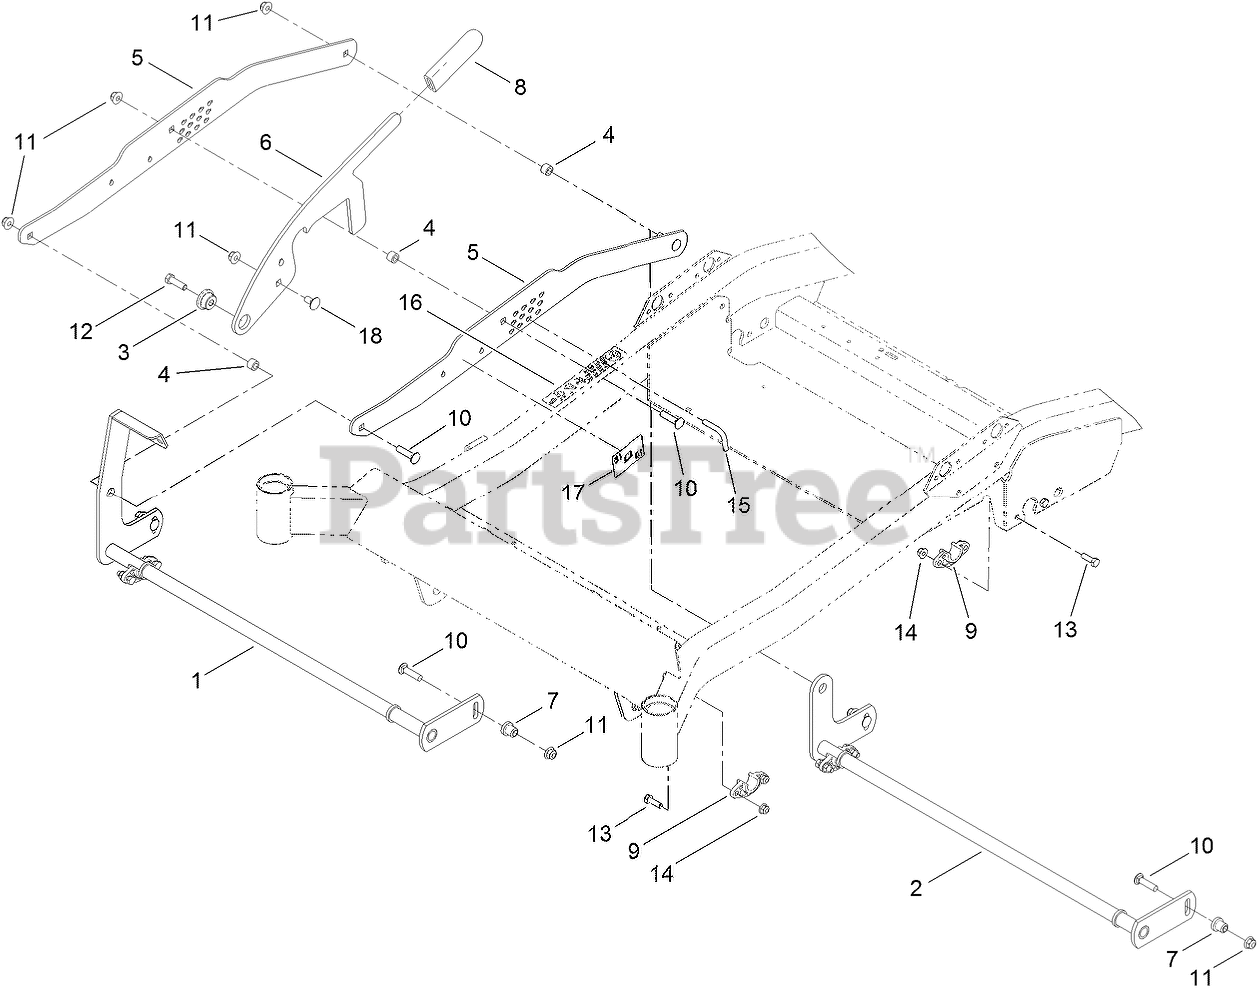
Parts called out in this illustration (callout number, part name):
1	PIVOT-FRONT
2	PIVOT-REAR
3	BUSHING-MOUNT, HOC
4	SPACER
5	PLATE-LIFT, FOOT
6	PLATE-STOP, HOC
7	BUSHING-PULLEY
8	GRIP-LEVER
9	BUSHING-FLANGE
10	SCREW-CARR
11	NUT-HF, NI
12	SCREW-HH
13	SCREW-HH
14	NUT-HF, NI
15	PIN-KEYED
16	DECAL-HOC
17	DECAL-LOCK, DECK
18	SCREW-CARR
